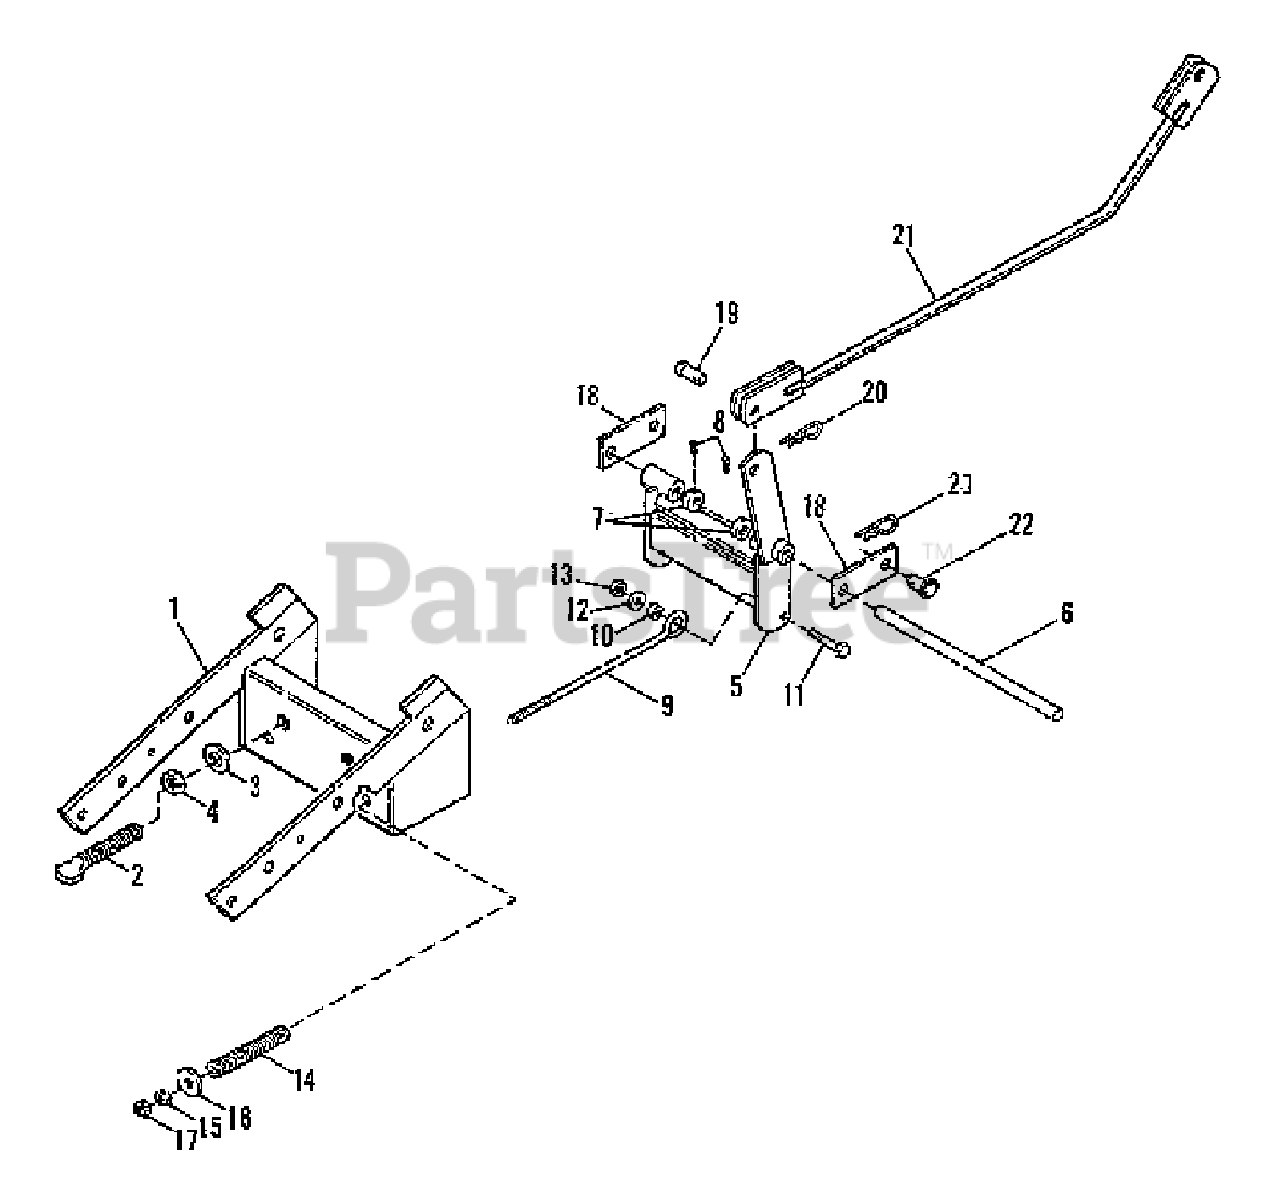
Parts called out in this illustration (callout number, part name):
1	HITCH ASSEMBLY, Blower
3	LOCKWASHER, 3/4 Standard
4	NUT, Hex, 3/4-10
5	HITCH ASSEMBLY
6	SHAFT, Inner
7	SET COLLAR
8	SET SCREW, Square Head, 5/16-18 x 1/2
11	CAPSCREW, Hex Head, 5/8-11 x 2
12	WASHER, Plain, 41/64 x 1-3/4
13	NUT, Hex, Centerlock, 5/8-11
14	SPRING, Compression
15	NUT, Hex, 3/8-16
16	WASHER, 3/8 x 1-3/4 x 1/4
17	NUT, Hex, Jam, 3/8-16
19	PIN, Clevis
20	CLIP, Hair Pin, 1/8 x 2-9/16
21	LIFT ROD ASSEMBLY
22	PIN ASSEMBLY
